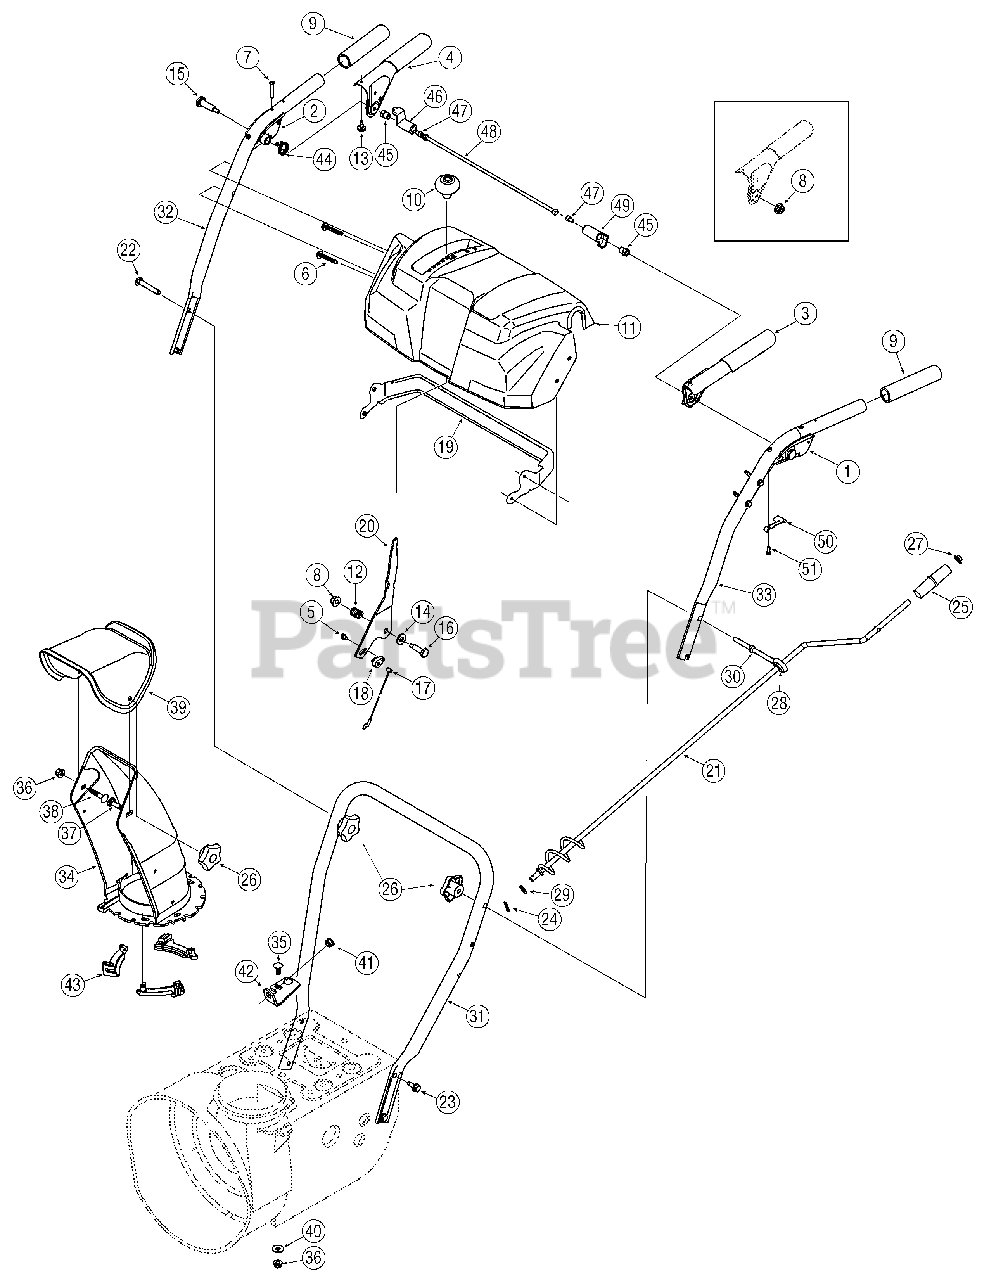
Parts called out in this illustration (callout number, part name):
1	Handle Assembly, Lock, LH
2	Handle Assembly, Lock, RH
3	Handle Ass’ y, Engagement LH
4	Handle Ass’y, Engagement, RH
5	Screw, #10-16, 0.500
6	Screw, 1/4-20, 1.625
7	Screw, Machine, #10-24, 1.375
8	Nut, Flange Lock, 1/4-20, Nylon
9	Grip, 1.0 ID x 5.0
10	Knob, Shift
11	Handle Panel, N-Style
12	Spring, .39 x .60 x .88
13	Bumper, Rubber, .62 OD x .22
14	Washer, Flat, 385 x .87 x .06
15	Screw, Shoulder, .43 x 1.34, 1/4-20
16	Screw, Shoulder, .374 Dia. x 1.05
17	Cable, Speed Selector
18	Barrel Holder, Cable, LH
22	Screw, Carriage, 5/16-18, 2.25
23	Screw, 5/16-18, 0.75, Gr5
24	Pin, Cotter, .072 x 1.13
25	Crank Knob, 1.0 Dia. x 3.2, Black
26	Star Knob
27	Cap, Push, 3/8 Rod
28	Grommet, .44 ID x .94 OD x .50
29	Washer, Flat, .375 x .738 x .063
30	Eye Bolt, Chute Crank
34	Chute, Lower, 5.0 Diameter
35	Bolt, Carriage, 5/16-18, 1.0
36	Nut, Flange Lock, 5/16-18, Nylon
37	Bolt, Carriage, 5/16-18, 1.0
38	Bolt, Carriage, 5/16-18, .750
39	Chute, Upper, w/ Label
40	Washer.349 ID x .879 OD x .063
41	Bushing, Plastic, .380
43	Flange Keeper, Chute
44	Torsion Spring
45	Nut, Hex, 1/4-20
46	Lock Plate
47	Cap Screw 1/4-20 x .375
48	Pivot Rod
49	Clutch Lock Cam
50	Clutch Lock Spring
51	Screw #8-16 x .50
